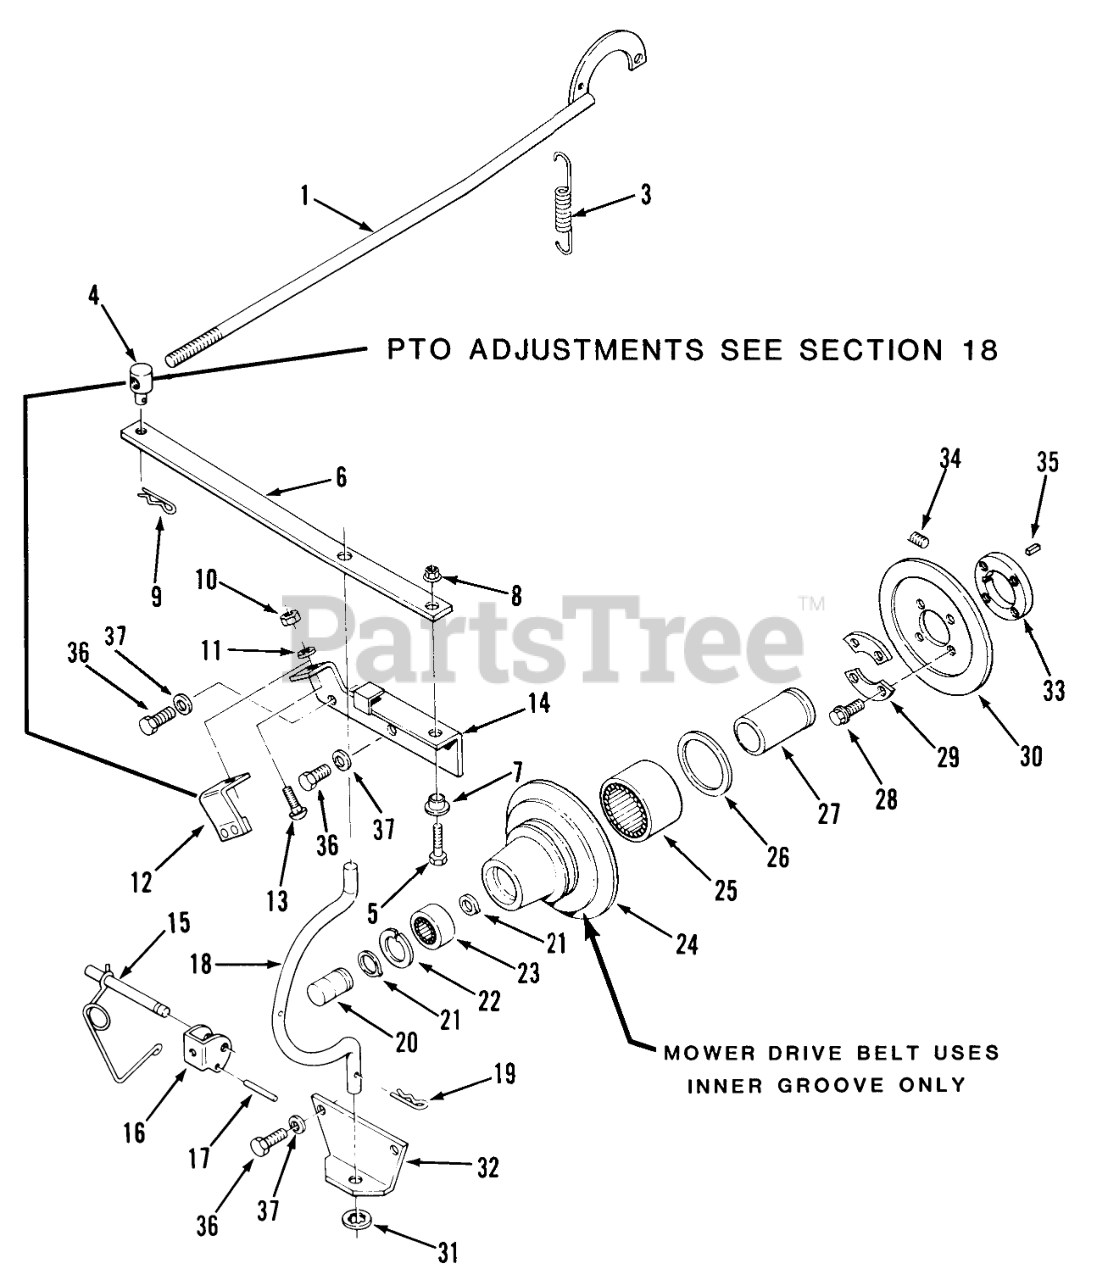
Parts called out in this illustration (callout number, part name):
1	PTO ROD 30209K
3	Spring
4	TRUNNION
5	BOLT
6	PTO ENG BRKT 30210K
7	SPACER-LIFT LINK
8	Nut
9	Hairpin Cotter
10	Nut
12	ASM-Bracket
13	Bolt-Carriage
14	Engine Bracket
15	LOCKING PIN ASM
16	CLEVIS B
18	ROD-HOUSING
19	Hairpin
20	SHAFT-PTO
21	RING-SNAP, EXTERNAL
22	Ring-Snap
23	BEARING-BALL
24	Housing-Clutch
25	BRG-NEEDLE OPEN END
26	SEAL-OIL
27	RACE-BEARING
28	H H C S
29	RETAINER
30	Clutch Plate & Facing
31	RING-REINFORCED CIRC
32	Rod Support Housing
33	PULLEY
34	Set Screw
36	7/16-14 x 1 1/4 Bolt
37	LOCKWASHER
